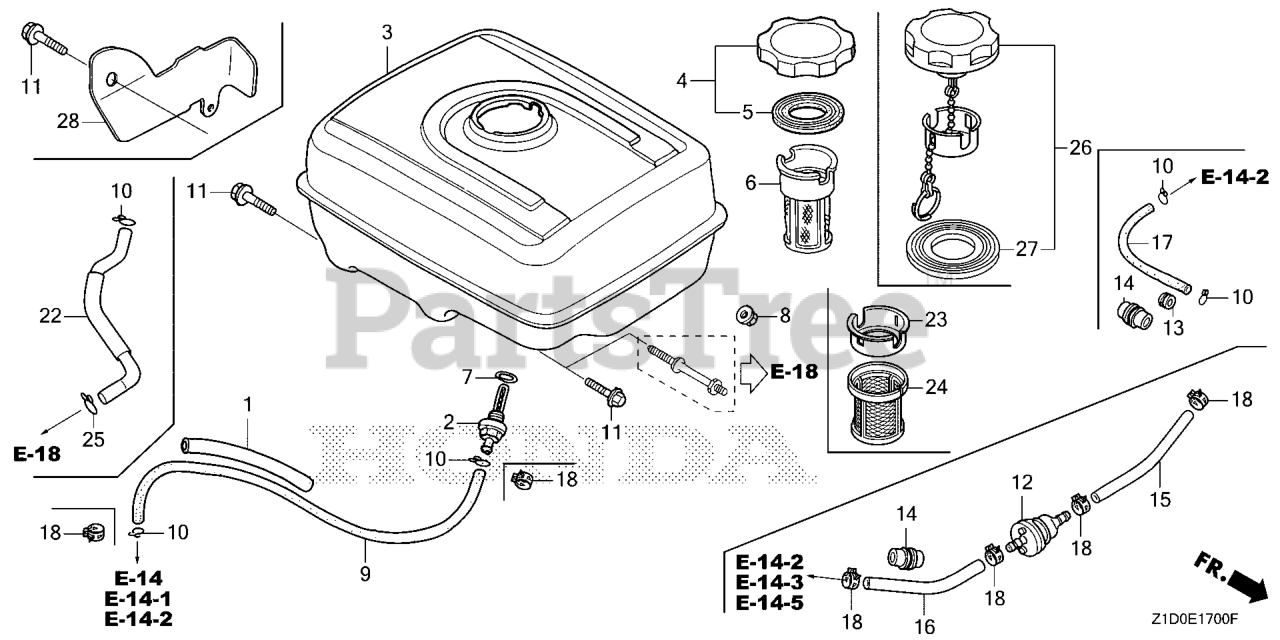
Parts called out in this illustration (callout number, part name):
1	RUBBER, SUPPORTER (107MM)
2	JOINT, FUEL TANK
3	TANK, FUEL *NH1* (BLACK)
3	TANK, FUEL *NH31* (MCKINLEY WHITE)
7	O-RING (14MM) (ARAI) Use up to Engine SN 2949254.
8	NUT, FLANGE (8MM)
9	TUBE, FUEL (4.5X210) (FKM)
11	BOLT, FLANGE (8X25)
18	CLIP, TUBE (D8)
24	FILTER, FUEL (FROM 1204807)
26	CAP, FUEL FILLER
27	GASKET, FUEL FILLER CAP
